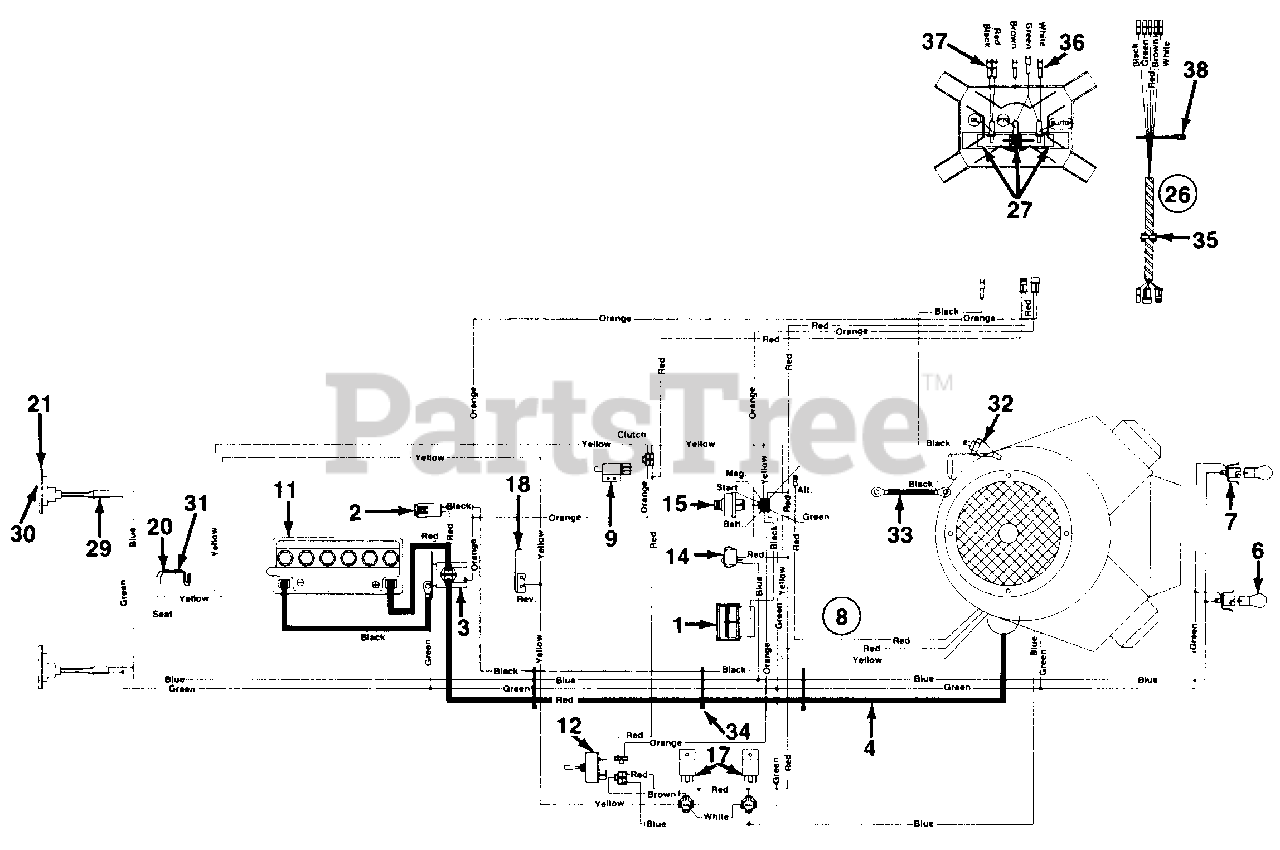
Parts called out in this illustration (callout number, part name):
1	Ammeter
2	Fuse 20 Amps
3	Solenoid
4	Wire 30" Lg.
6	Bulb
7	Socket
8	Wire Harness
9	Safety Switch (Clutch)
11	Battery 12V (275 Cold Crank Amps)
12	Switch (PTO)
14	Light Switch
15	Ignition Switch
17	Relay
18	Spring Lever
20	Safety Switch (Seat)
21	Taillight
26	Monitor Shaft Harness
27	Bulb
29	Taillight Harness
31	Safety Switch (Seat)
32	Oil Pressure Switch
33	Wire 7.5" Lg.
34	Cable Tie
35	Wire Clip
36	Monitor Light Harness Dual
37	Monitor Light Harness Single
38	Cable Tie
